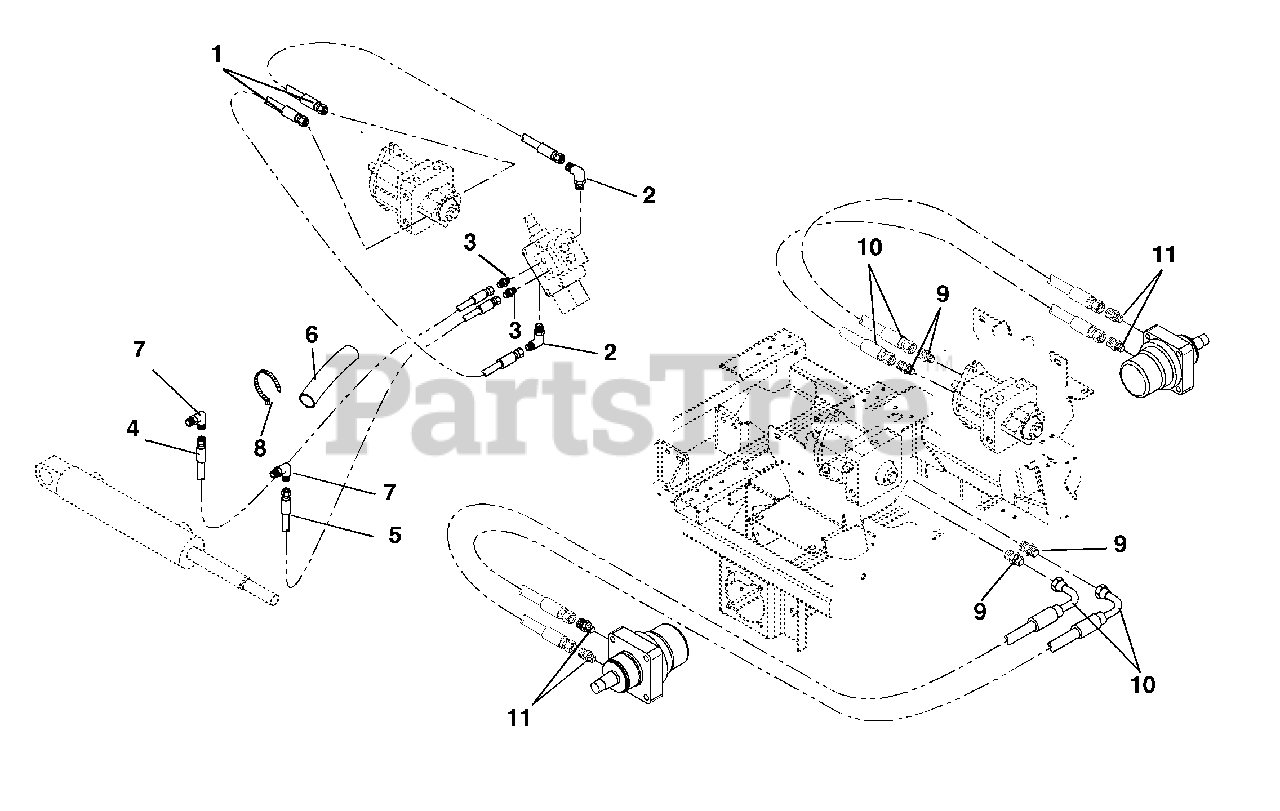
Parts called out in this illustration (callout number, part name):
1	Hose, Hydraulic
2	Hydraulic, Fitting Elbow
4	Hose, Hydraulic
5	Hose, Hydraulic
6	Sleeve Protective 24"
7	Fitting, Hydraulic
8	Cable Tie
9	Adapter, Face Seal 8 x 8 .50 O-Ring
10	Hose, Hydraulic .50
11	Adapter-Hydraulic Steel .875 to .75
